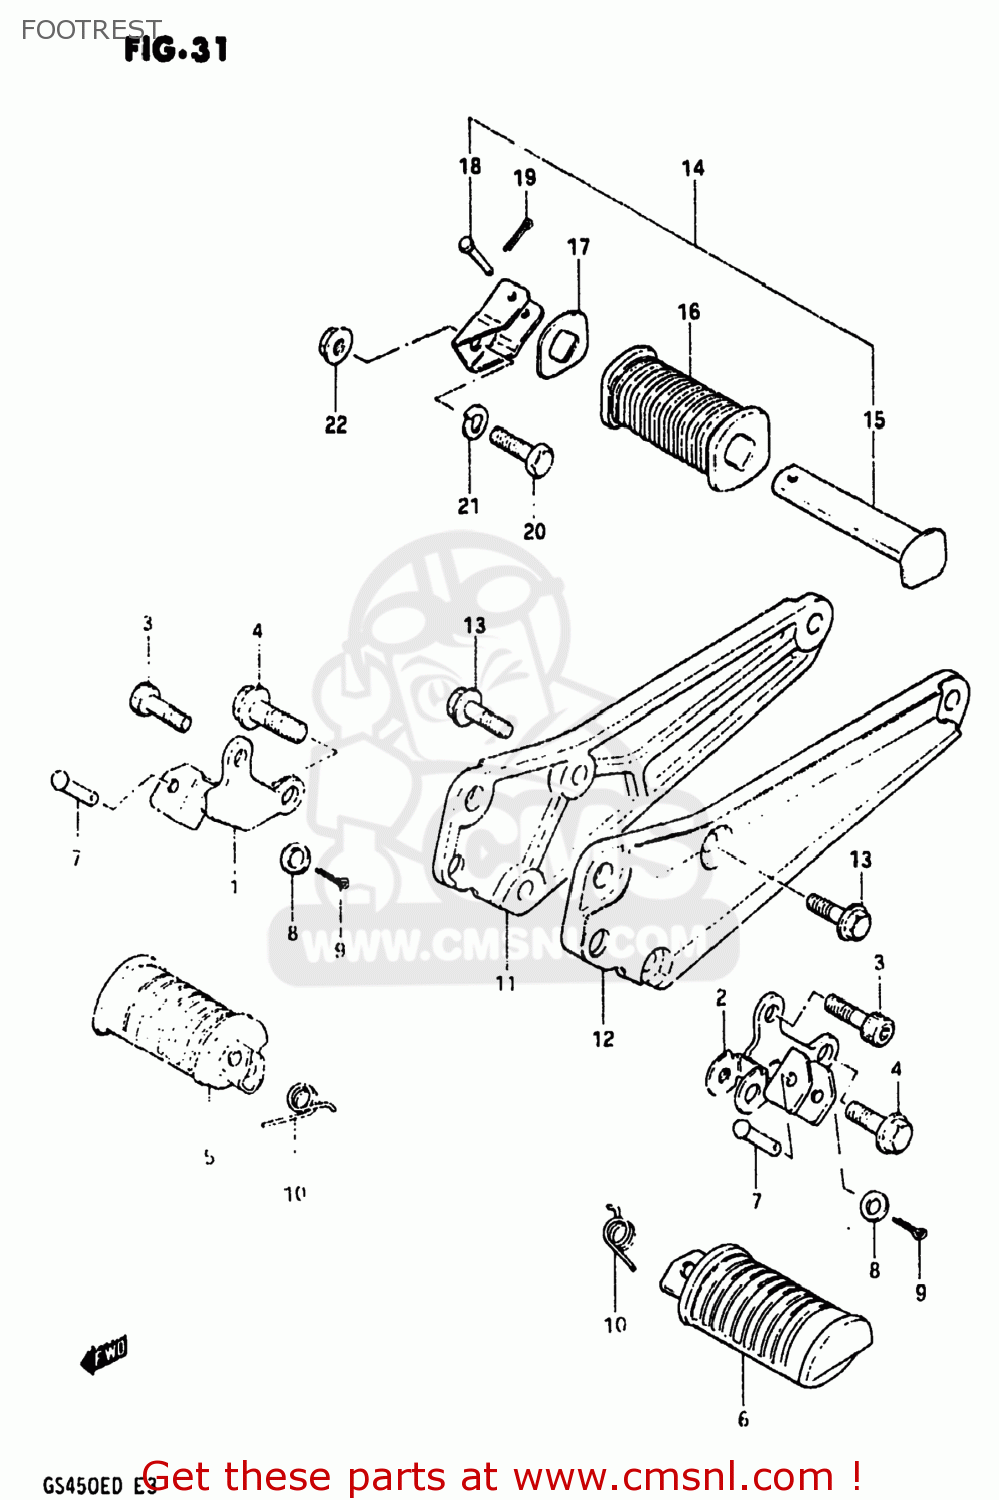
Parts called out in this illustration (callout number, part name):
1	BAR,FRONT FOOTREST
2	BAR,FRONT FOOTREST,LEFT
3	BOLT
4	BOLT
5	RUBBER,PILLION FOOTREST,R
6	RUBBER,PILLION FOOTREST,L
7	PIN
8	WASHER
9	PIN 20X20
10	SPRING
11	BRACKET,MUFFLER,RIGHT
12	BRACKET,MUFFLER,LEFT
13	BOLT
14	FOOTREST ASSY,PILLION,R
15	BAR,REAR FOOTREST,LEFT
16	RUBBER,PILLION FOOTREST
17	WASHER,FOOTREST RUBBER
18	PIN
19	PIN 20X20
20	BOLT,M10X1.25X
21	LOCK WASHER
22	NUT
